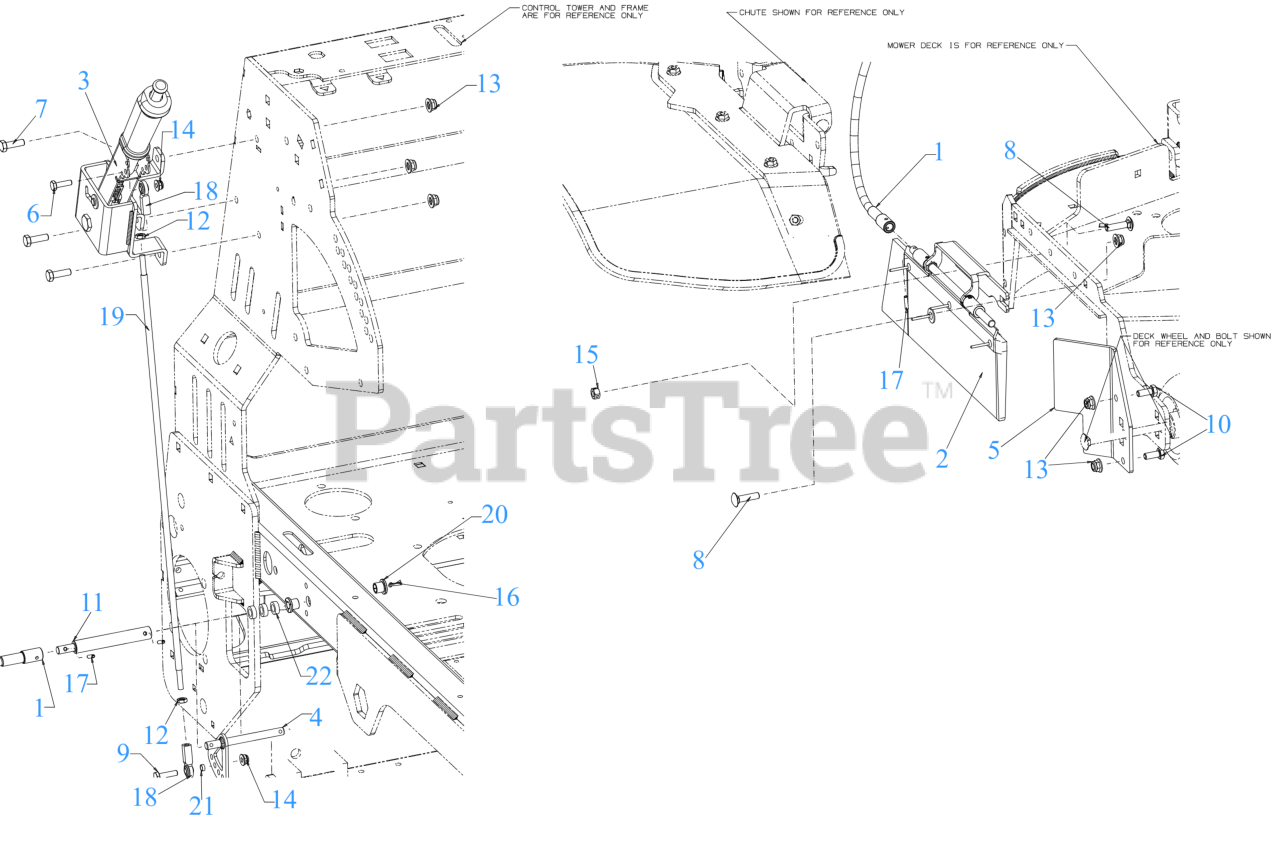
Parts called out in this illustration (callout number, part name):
1	CHUTE CONTROL CABLE ASSEMBLY
2	DISCHARGE DOOR ASSEMBLY
3	DOOR HANDLE
4	DOOR SHAFT
5	BRACKET
6	HEX SCREW 1/4-20 x .875 GR5
7	SCREW 5/16-18 x 1.0 GR5
8	CARRIAGE BOLT 5/16-18 x 1.25
9	SCREW 1/4-20 X1.00 GR5
10	SCREW 5/16-18 x .75 GR5
11	ADAPTER SHAFT 4.25"
12	HEX JAM NUT 1/4-28
13	FLANGE LOCK NUT 5/16-18
14	FLANGE LOCK NUT
16	COTTER PIN
17	ROLL PIN 5/32" x .688"
18	END ROD (RH)
20	FLANGE BEARING
22	SPACER-.380 ID x .625 OD x .227
